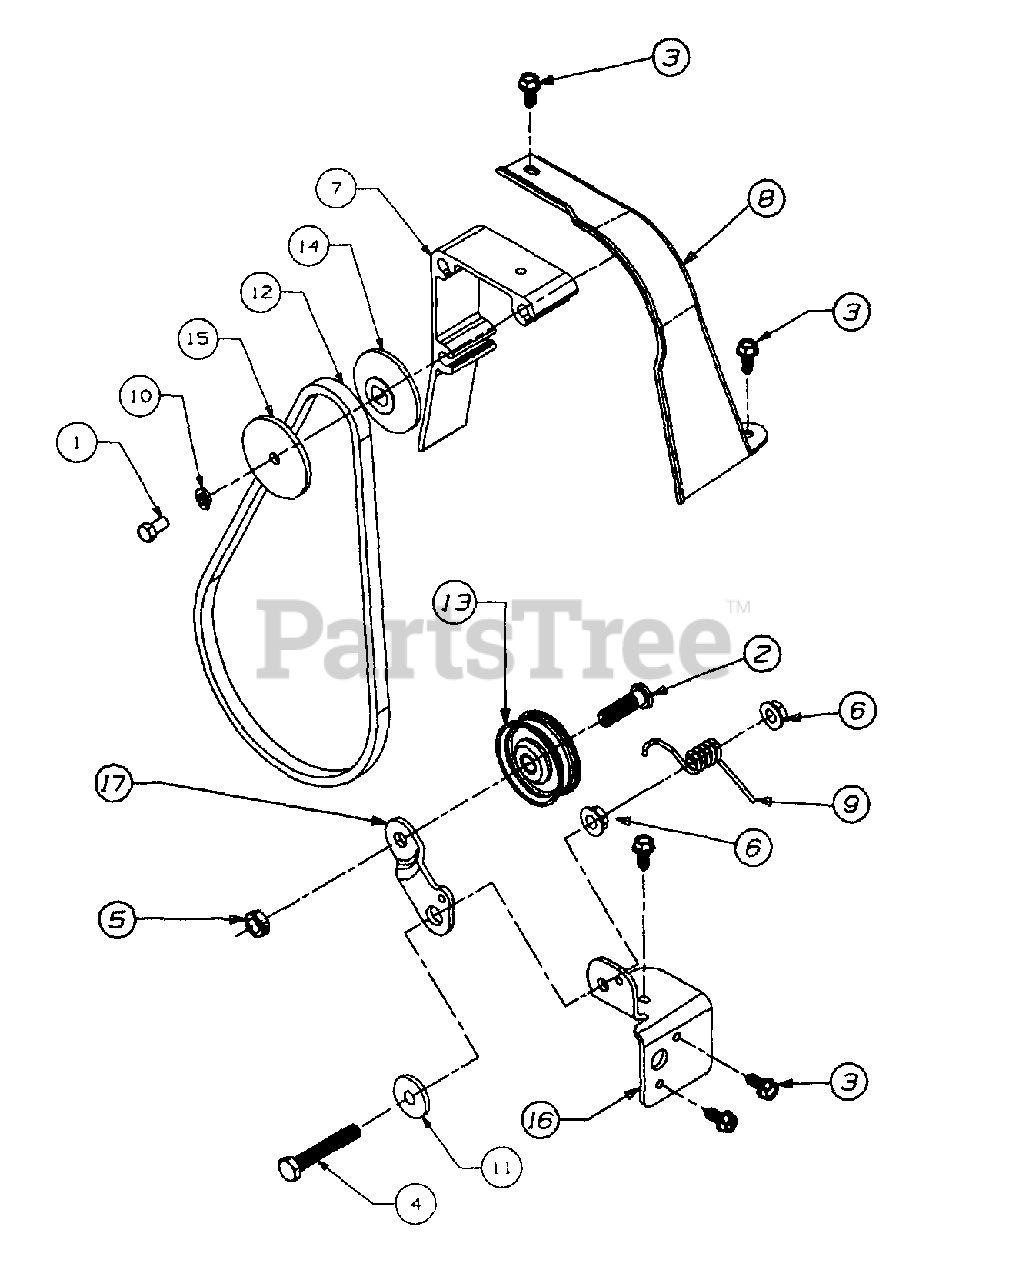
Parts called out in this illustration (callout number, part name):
1	SCREW-HEX
2	SCREW-HEX
3	SCREW-HEX
4	SCREW-HEX
5	NUT-HEX LOCK
6	NUT-HEX LOCK FL
7	ADAPTER-MOUNTING
8	COVER-BELT
9	SPRING-TORSION
10	WASHER-LOCK
11	SHOULDER SPACER
12	V-BELT
13	IDLER-FLAT
14	PULLEY
15	PULLEY
